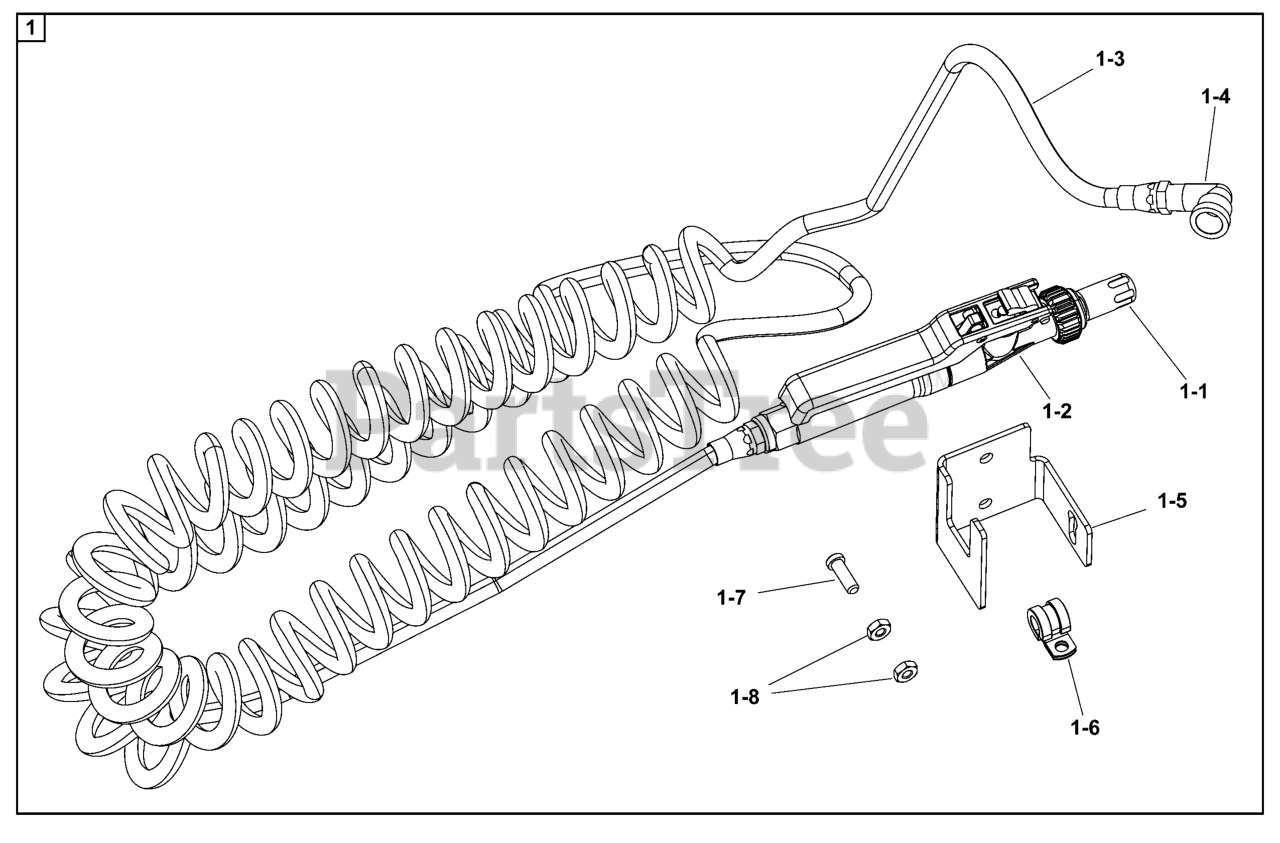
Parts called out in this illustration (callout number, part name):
1	ASSY, SPRAY WAND (SPW-200-1)
1-1	NOZZLE, SPRAY WAND (G0169)
1-2	SPRAY GUN, 1/4 FPT
1-3	HOSE, COIL 25 FT
1-4	STREET ELBOW, 1/4 MPT-1/4 FPT, 90 DEG
1-5	BRACKET, SPRAY WAND HOLDER
1-6	CLAMP, SPRAY WAND LOOP
1-7	SCR-CAP, SHLP .250-20 X .750" G8 ZP
1-8	NUT-HEX, JAM .250"-20 SS188
